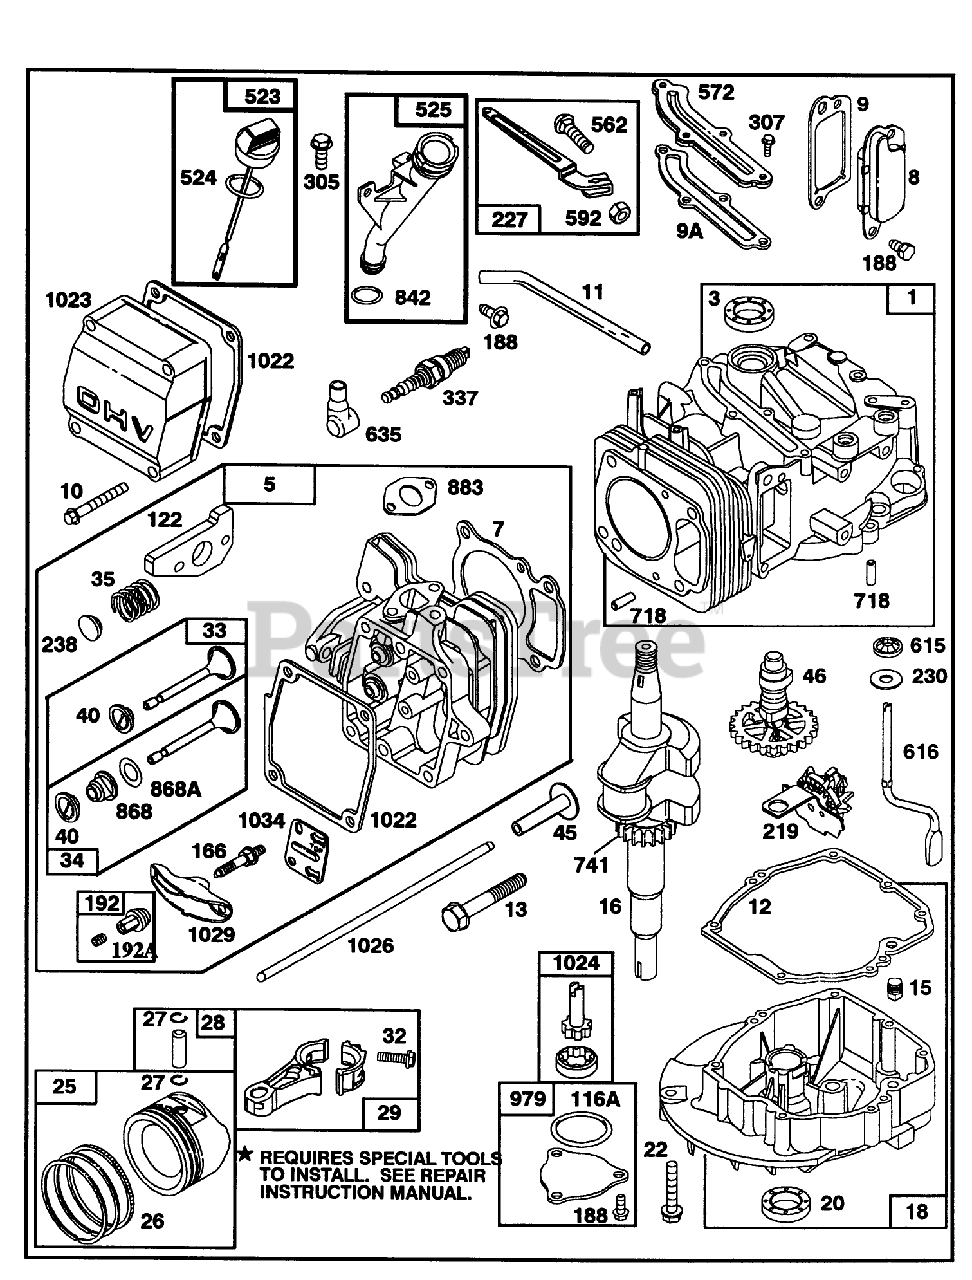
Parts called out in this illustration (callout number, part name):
3	SEAL - OIL
7	CYLINDER HEAD GASKET
9	Gasket-Breather
9A	GASKET-BREATHER
12	ENGINE BASE GASKET
20	SEAL-OIL
104	FLOAT HINGE PIN
116	SEALING GASKET
116A	O RING SEAL
118	VALVE KIT - NEEDLE
121	CARBURATOR OVERHAUL KIT
122	ADAPTER ASSEMBLY
134	Valve-Float (Includes Seat)
137	FLOAT BOWL GASKET
163	AIR CLEANER GASKET
358	GASKET SET
524	O-RING
634	SEAL WASHER
842	O-RING
868	SealAssy-Valve
868A	Seal-Valve
883	EXHAUST GASKET
977	CARBURATOR GASKET SET
1022	ROCKER COVER GASKET
1039	FLOAT LIMITER
1041	SEAL - FOAM
